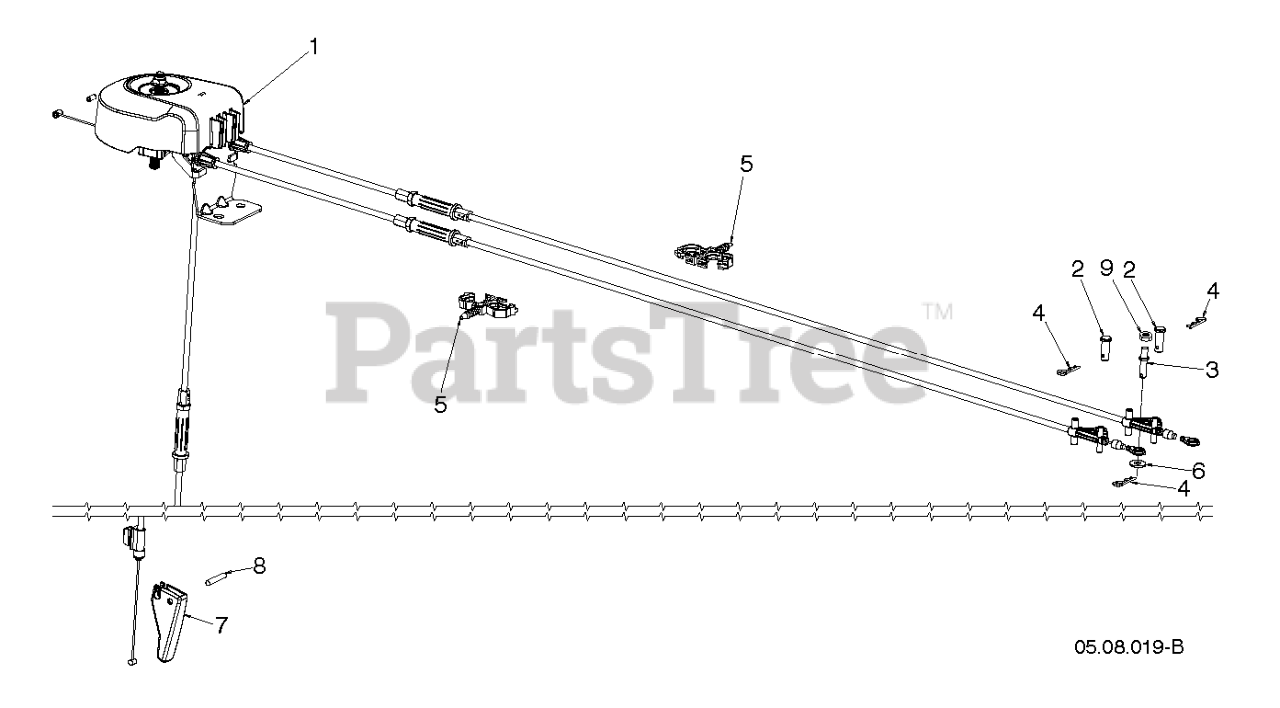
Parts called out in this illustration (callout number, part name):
1	CABLE ASSY CHUTE ROTATOR CLUTC
2	PIN CLEVIS 5/16X.875
3	Clevis Pins
4	HAIRPIN.SOFT.ZINC.059X1.125
5	CLIP.CONDUIT.DOUBLE LOOP
6	WASHER FLAT_.250 X .625 X .06
8	PIN, ROLL 3/16 X 1-1/8
9	NUT HEXAGON 1/4-20 ST ZPB
